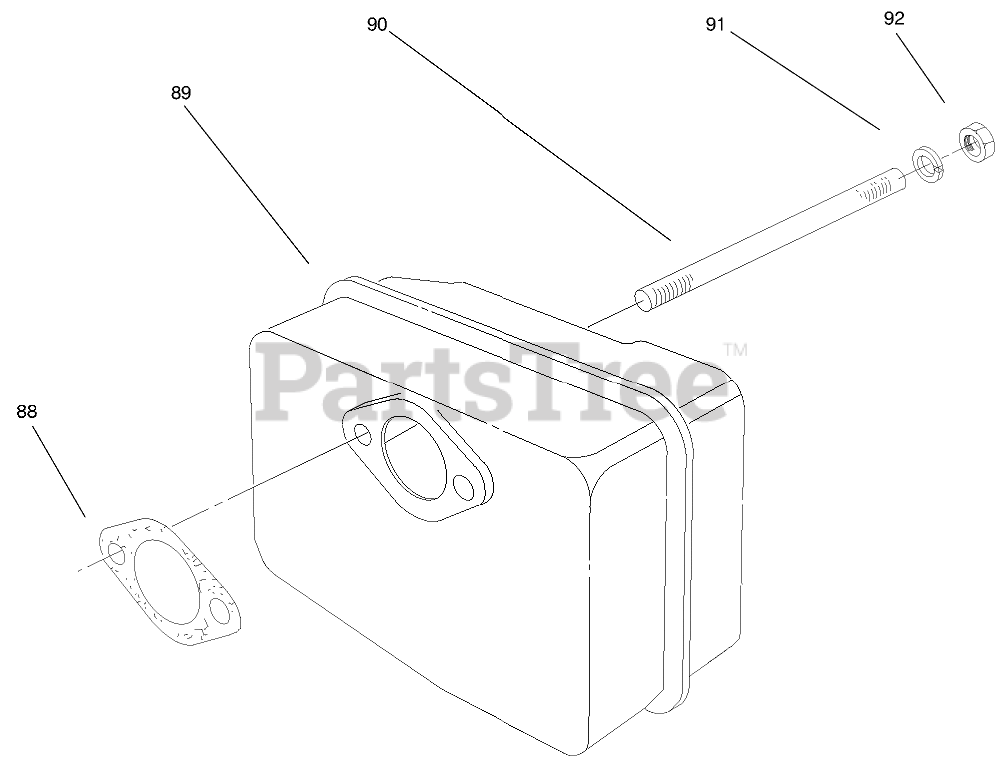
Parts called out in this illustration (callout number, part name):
78	SCREW
79	GASKET
88	GASKET
89	MUFFLER
91	WASHER-LOCK
